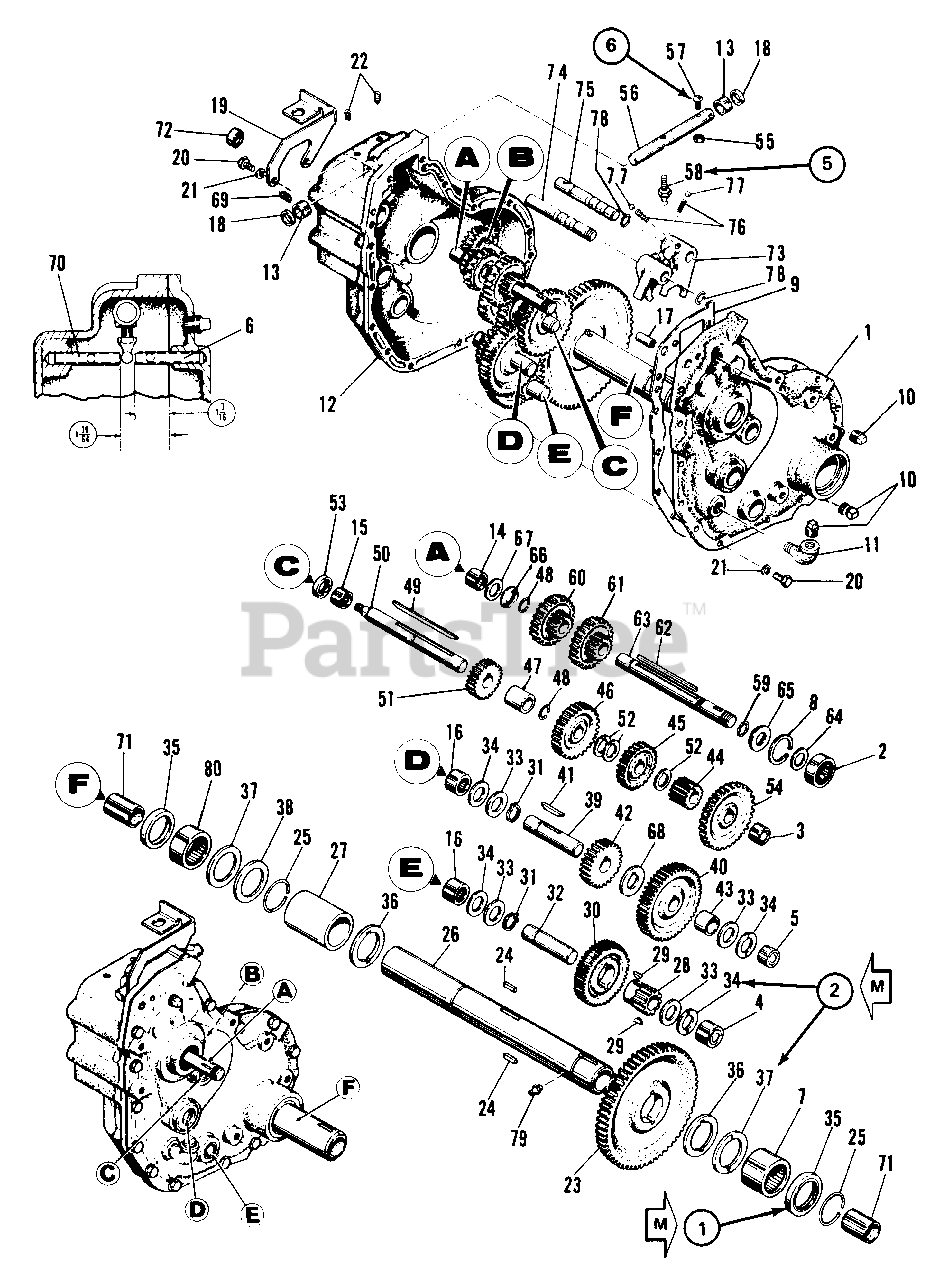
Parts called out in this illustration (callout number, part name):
1	COVER, Gear Case
2	BEARING, Ball
3	BEARING, Needle
4	BEARING, Needle
5	BEARING, Needle
6	ROLL PIN ASSEMBLY
7	BEARING, Needle
8	RING, Retaining
9	GASKET, Gear Case
10	PLUG, Pipe, Sq. Hd., 3/8
11	ELBOW, Street
12	GEAR CASE ASSEMBLY
13	SPACER, Diff.
14	BEARING, Needle
15	BEARING, Needle
16	BEARING, Needle
17	PIN, Spring, 3/8x 1
19	SUPPORT, Switch
20	CAPSCREW, Hex Hd., 5/16-18 x 1
21	LOCKWASHER, 5/16
22	SETSCREW, Soc. Hd., 5/16-18 x 1/2
23	GEAR, Drive
26	TUBE & BUSHING ASSEMBLY (Includes Ref. No. 71)
27	SPACER, Axle Tube
28	PINION, 3rd Interm.
29	KEY, Woodruff, No. 6
30	GEAR, 3rd Interm.
31	RING, Retaining
32	SHAFT, 3rd Interm.
36	WASHER, Axle Tube
37	WASHER, Axle Tube
38	WASHER, Axle Tube
39	SHAFT, 2nd Interm.
40	GEAR, 2nd Interm.
42	PINION, 2nd Interm.
44	PINION, 1st Interm.
45	PINION, Driver III
46	GEAR, Driver II
48	RING, Retaining
50	SHAFT, 1st Interm.
51	PINION, Rev. & IV
54	GEAR, Driven I
55	NUT, Jam Hex, 5/16-18
56	ROD, Shift
57	BOLT CARRIAGE, Special
58	STEM, Shift
59	RING, Retaining
60	GEAR ASSY
61	PINION ASSEMBLY I & II
63	SHAFT, Pulley
69	SCREW, Set. 3/8-16 x 3/8
70	ROLL PIN ASSY
71	BEARING, Needle
72	PLUG, Expansion
73	FORK, Shift
74	SHAFT, Shifter
75	SHAFT, Shifter, Hi-Lo
77	BALL, Shiftlock
78	RING, Retaining
79	FITTING, Grease
80	BEARING, Needle
